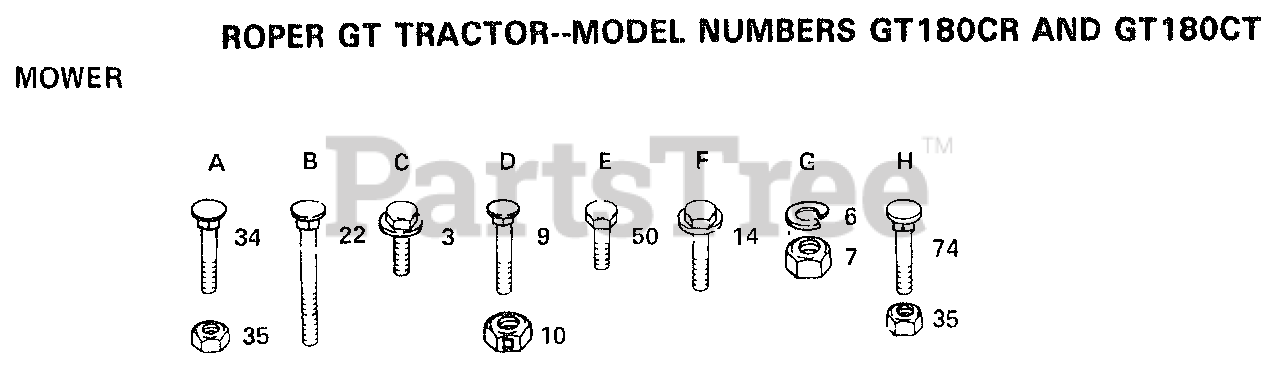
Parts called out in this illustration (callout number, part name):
6	LOCKWASHER
7	NUT.HEX.5/16-18
9	BOLT
14	SCREW
22	BOLT
34	BOLT
50	BOLT
74	BOLT
